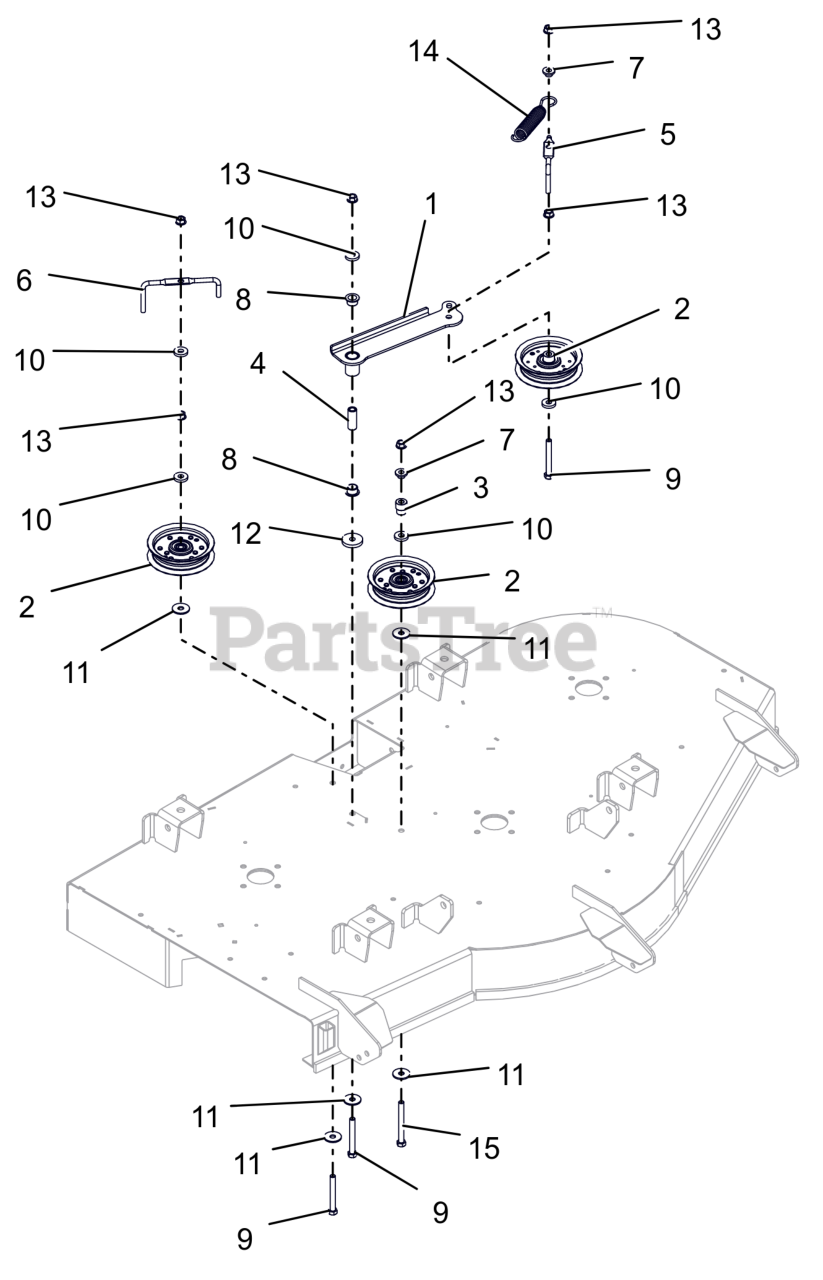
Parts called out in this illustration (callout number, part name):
1	WLDMT, IDLER ARM-52"
2	ASM, IDLER 4"
3	BUSHING, IDLER (P/M)
4	SPACER, .375IDX.625ODX1.66 PM
5	WIREFORM, BELT FINGER
6	WIREFORM, BELT FINGER
7	BSHG-FLG .385X.500X.875X.406
8	BSHG-FLG, .625X.750X.500X1.00
9	BLT, HEX .38-16X3.00F G5 ZCC
10	WSHR, FLT .406X1.00X.188 ZCC
11	WSHR FL STL .406X1.25X.10ZC120
12	WSHR, FLT .406X1.50X.245 ZCC
13	NUT-LK-CTR-FLG .375-16 GF ZCC
14	SG-TENS .135X.98X6.0 WLD 62
15	BLT, HEX .38-16X3.50 G5 ZCC
